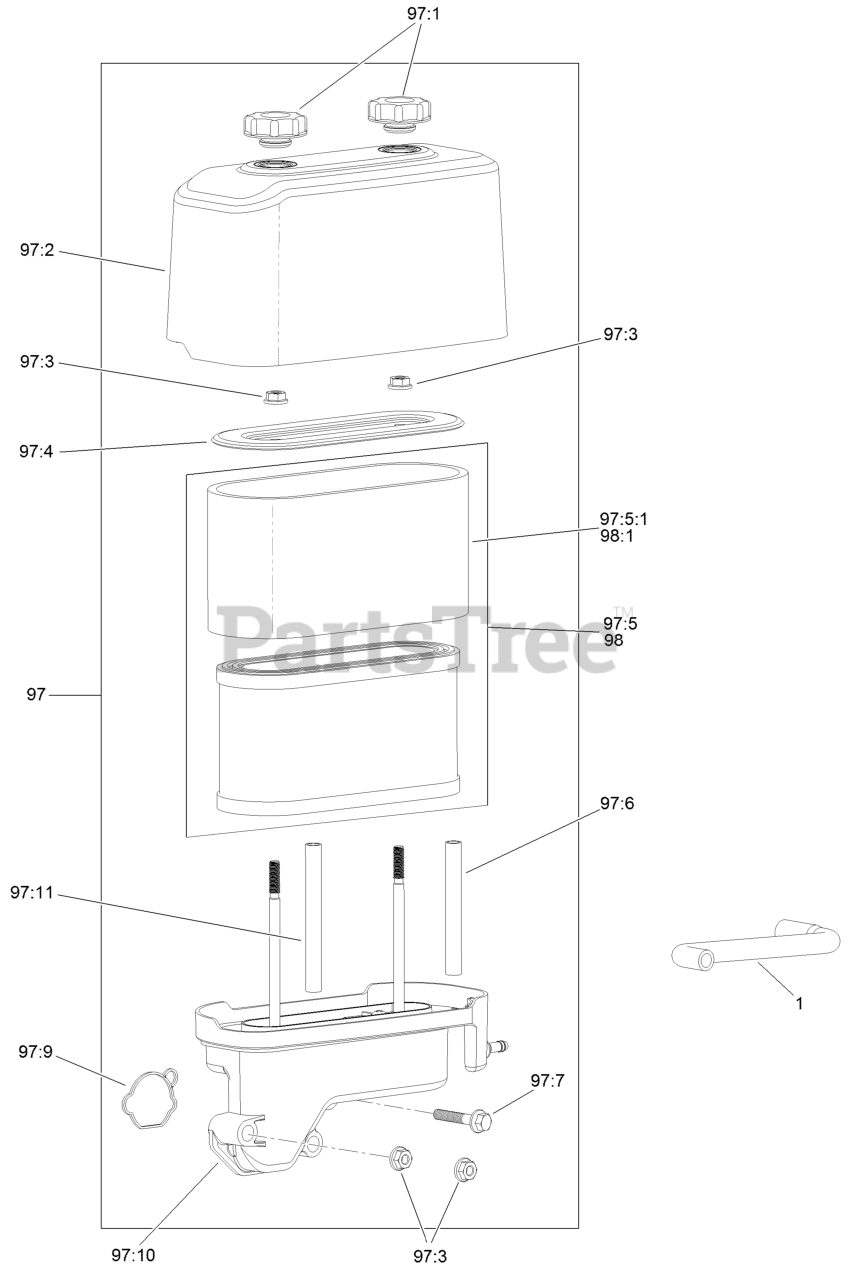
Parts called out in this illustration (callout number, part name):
1	TUBE-BREATHER
97:1	NUT-SPEED
97:2	COVER-FILTER, AIR
97:3	NUT-FLANGE
97:5:1	PREFILTER
97:6	SPACER-FILTER, AIR
97:7	SCREW-HHF
97:9	GASKET-CARBURETOR
97:11	SPACER-FILTER, AIR
98:1	PREFILTER
